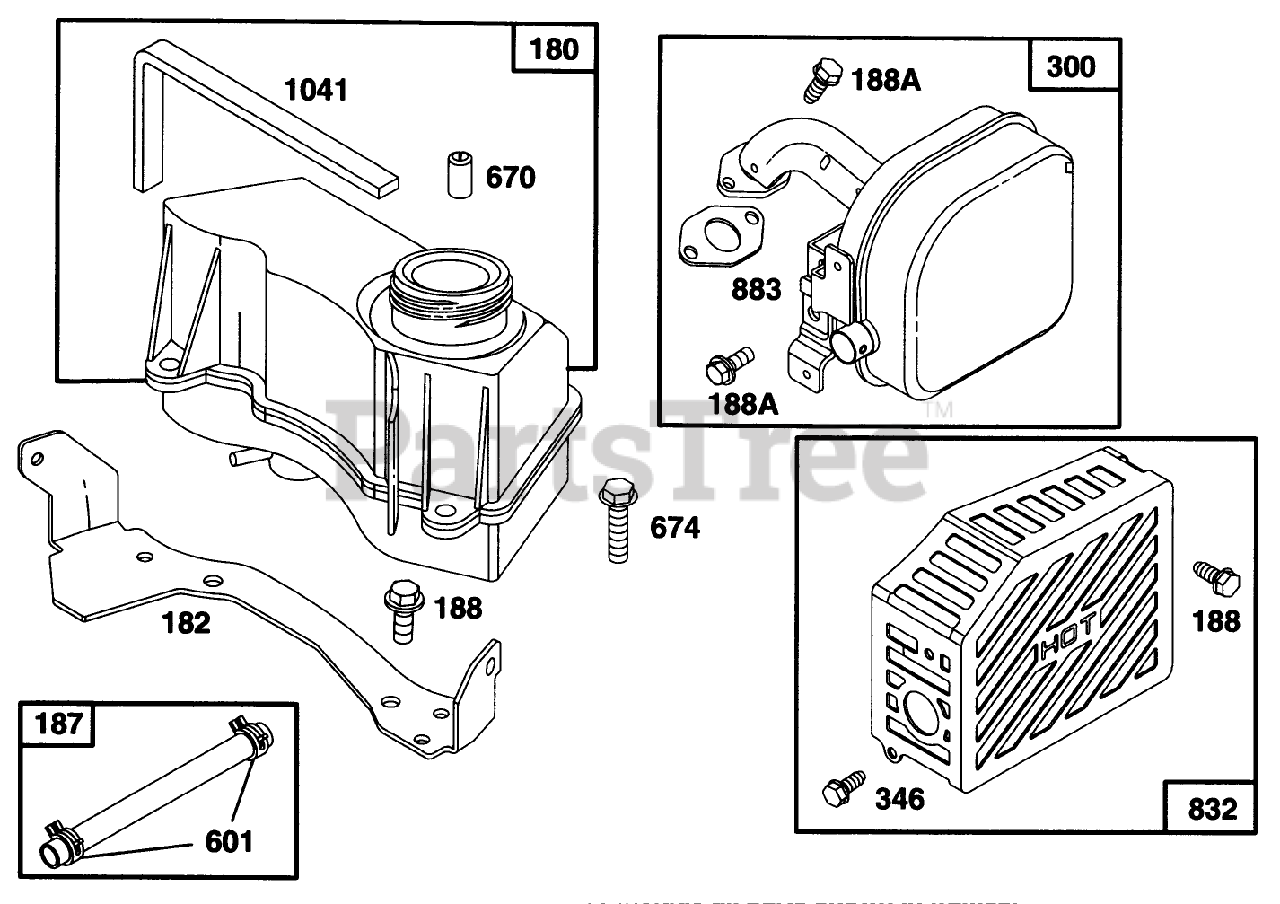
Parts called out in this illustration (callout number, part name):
180	TANK ASSY - FUEL
187	BRIGGS 296004
188	SCREW - HEX HEAD
188A	Screw-Sem
300	MUFFLER - EXHAUST
601	CLAMP - CL PIPE
670	SPACER
674	SCREW - HEX HEAD
